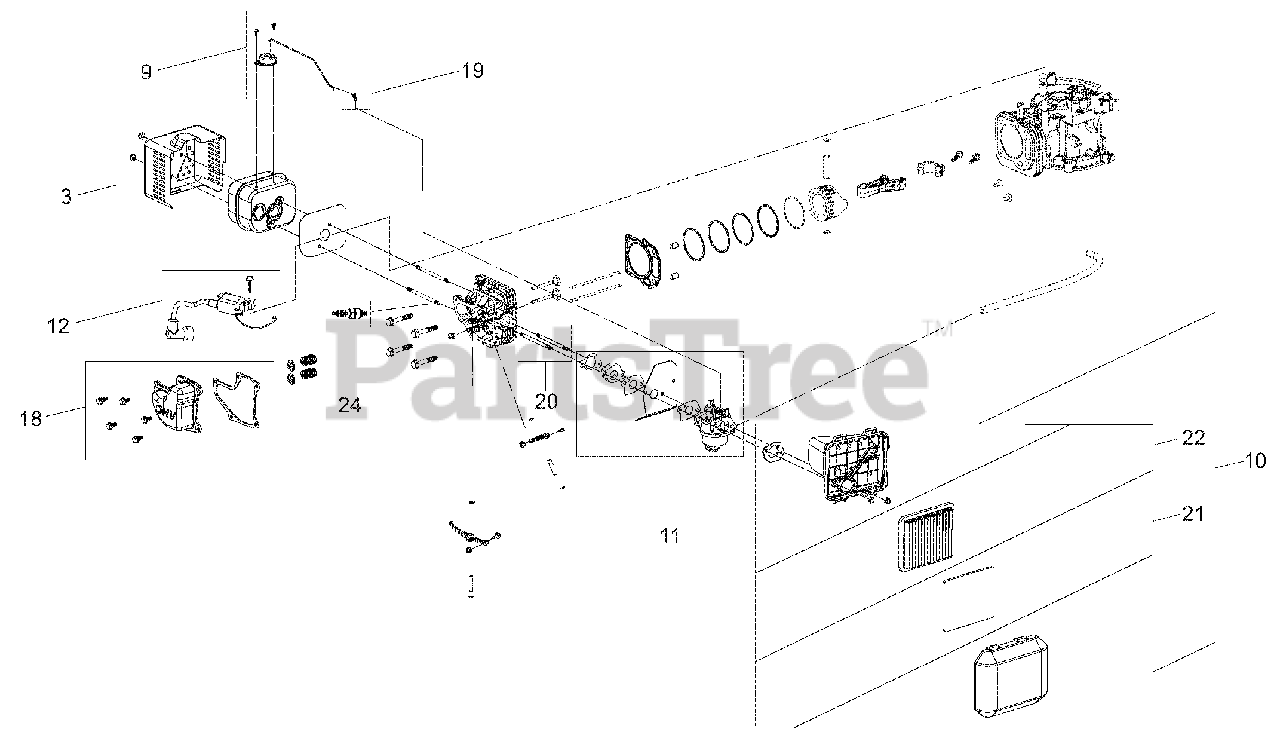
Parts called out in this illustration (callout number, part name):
3	KIT, MUFFLER AND SHIELD - SVC
9	KIT, THERMAL CHOKE CONTROL-SVC
10	KIT, AIR CLEANER ASM - SVC
11	KIT, CARBURETOR COMPLETE - SVC
12	KIT, IGNITION COIL - SVC
13	KIT, SEAL AND GASKET - SVC
16	KIT, STARTER - SVC
17	KIT, WIRE HARNESS - SVC
18	KIT, VALVE COVER - SVC
19	LOCK, THROTTLE - SVC
20	STUD, INTAKE - SVC
21	ELEMENT, AIR CLEANER
22	FILTER, AIR - LONCIN 160CC
24	SPARK PLUG, LONCIN 160CC
29	ENGINE,SERVICE,AC SERIES
29	ENGINE,SERVICE,AC SERIES,ELEC
